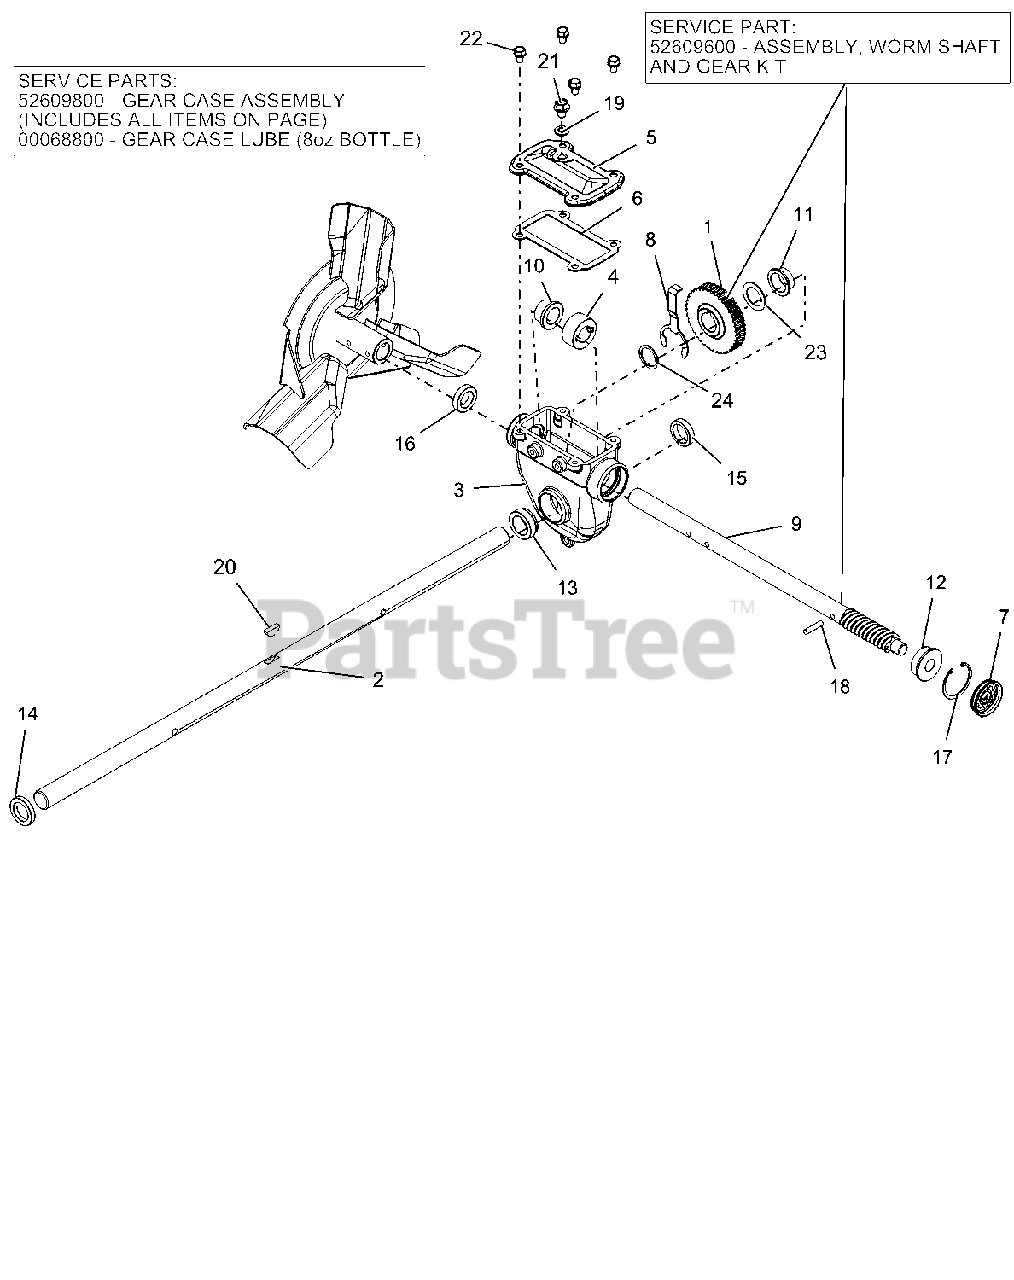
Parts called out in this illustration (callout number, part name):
1	WORM GEAR
2	SHAFT, RAKE-32"
3	GEARCASE, LARGE MACHINED
4	THRUST COLLAR, .875"ID SLIPFIT
5	COVER, TOP - LARGE IRON
6	GASKET, TOP - LARGE GEARCASE
7	COVER, GEAR CASE 1.75"
8	BUSHING RETAINER, LARGE
9	SHAFT, WORM - PRO
10	BSHG-FLG .879X1.128X.75X1.45
11	BSHG-FLG 1.006X1.128X.555X1.45
12	BSHG-FLG .628X1.503X.58X1.725
13	BSHG-FLG LARGE, RIGHT
14	SEAL-OIL .999X1.500X.250 TBC29
15	SEAL-OIL .999X1.375X.312 TBC29
16	SEAL-OIL .873X1.375X.312 TBC29
17	RG-RTNG-INT 1.750X.062
18	PIN-STR .250X1.12 6150
19	WSHR-BND-SEAL .38X.75X.11 GALV
20	KEY-WDRF .25X.875 HRD #A
21	@SCR-ROLOK .38-16X.50 HWH YWZC
22	BOLT, SEMS .31-18X.50 GR5 YWZC
23	WSHR-FL-STL 1.010X1.505X.062YZ
24	WSHR-FL-STL 1.010X1.250X.068YZ
25	GEAR CASE, 32" IRON PRO TOP-LD
26	ARIENS L3 LUBE, 8 OZ BOTTLE
27	ASSY, WORM SHAFT & GEAR
